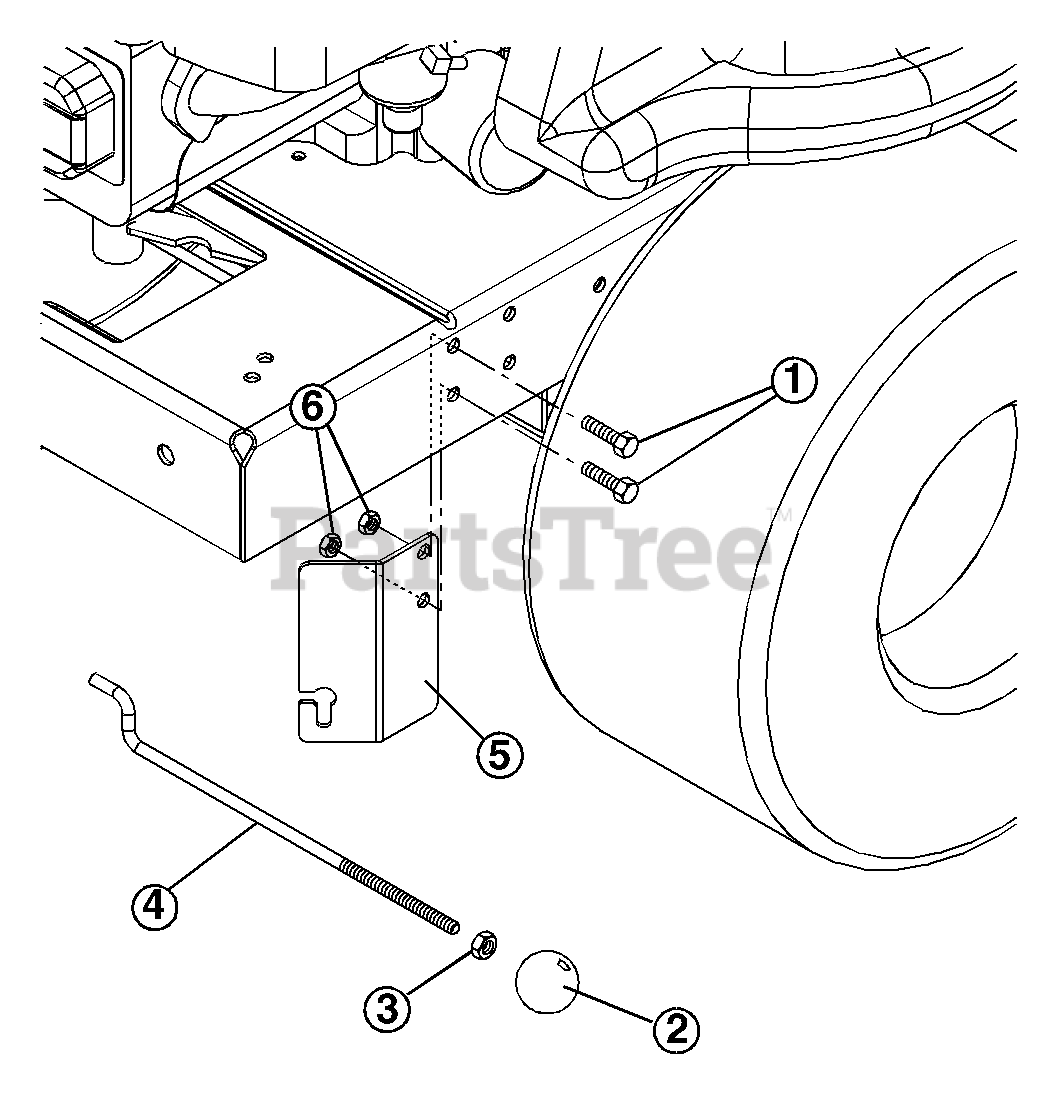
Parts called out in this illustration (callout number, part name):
1	3/8 - 16 x 1-1/4 Hex Bolt
3	5/16 - 16 Nut
4	Rod, Idler
5	Bracket, Cold Start
6	3/8 - 16 Lock Nut
